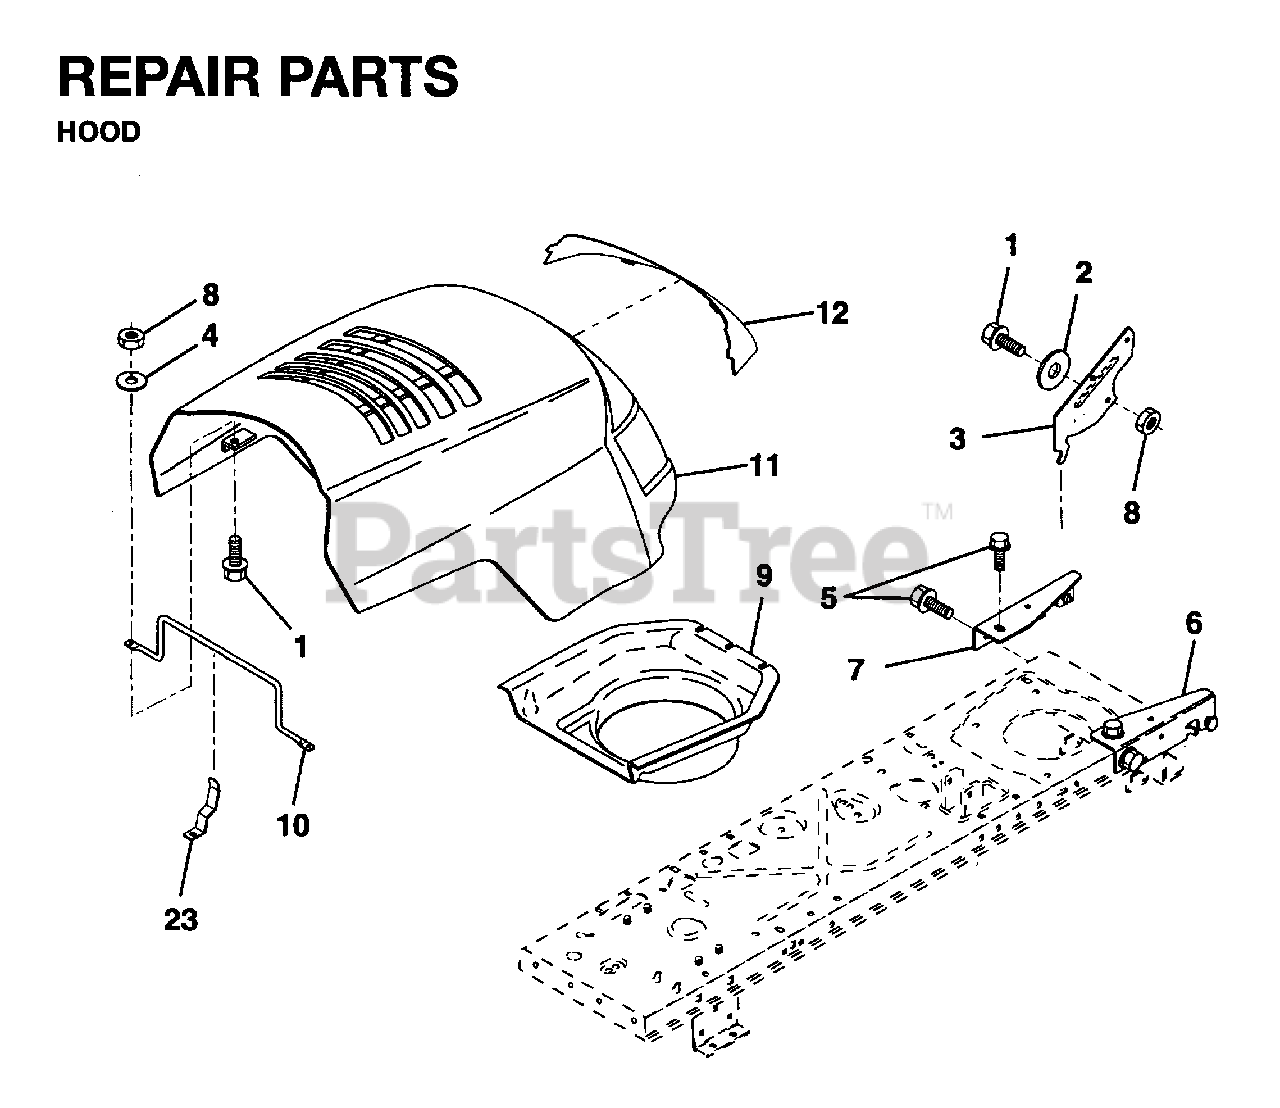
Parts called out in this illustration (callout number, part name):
5	BOLT
6	BRACKET ASSY HOOD
7	BRACKET ASSY
8	NUT.CROWNLOCK.1/4
23	HOOD LATCH
